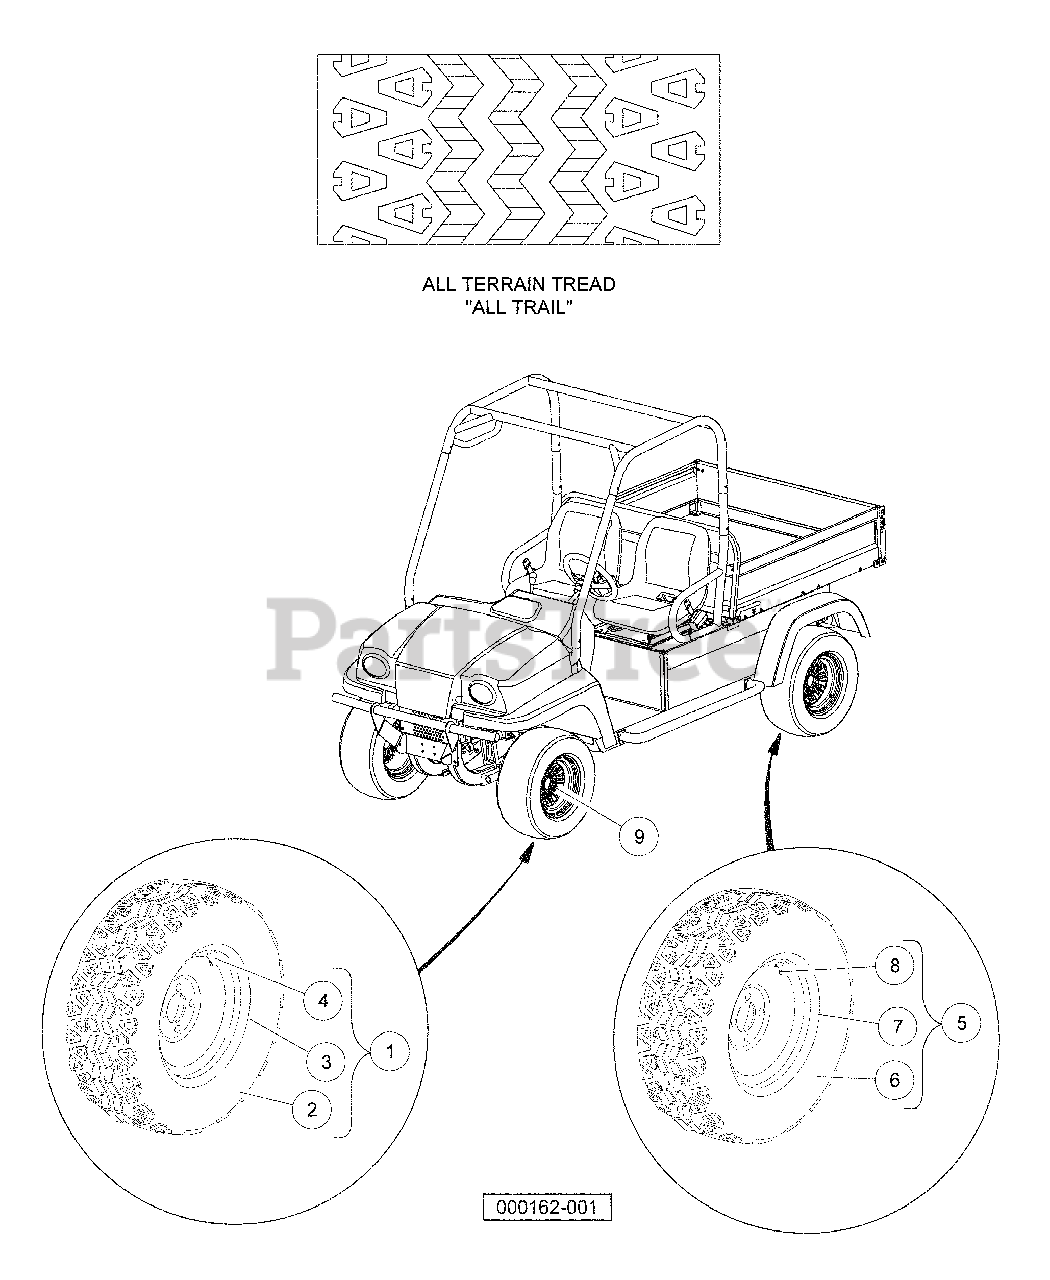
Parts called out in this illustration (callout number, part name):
1	Gray Tire Assembly, HDAT, 8-Inch
2	HDAT Tire, 8"
3	Wheel, Indus Spider, Gray
4	Valve Stem
5	Gray Tire Assembly, HDAT 10.5-Inch
6	Tire, HDAT
7	Wheel, Indus Spider, Gray
8	Valve Stem
9	Nut, Lug, 1/2-20 SAE J2283
